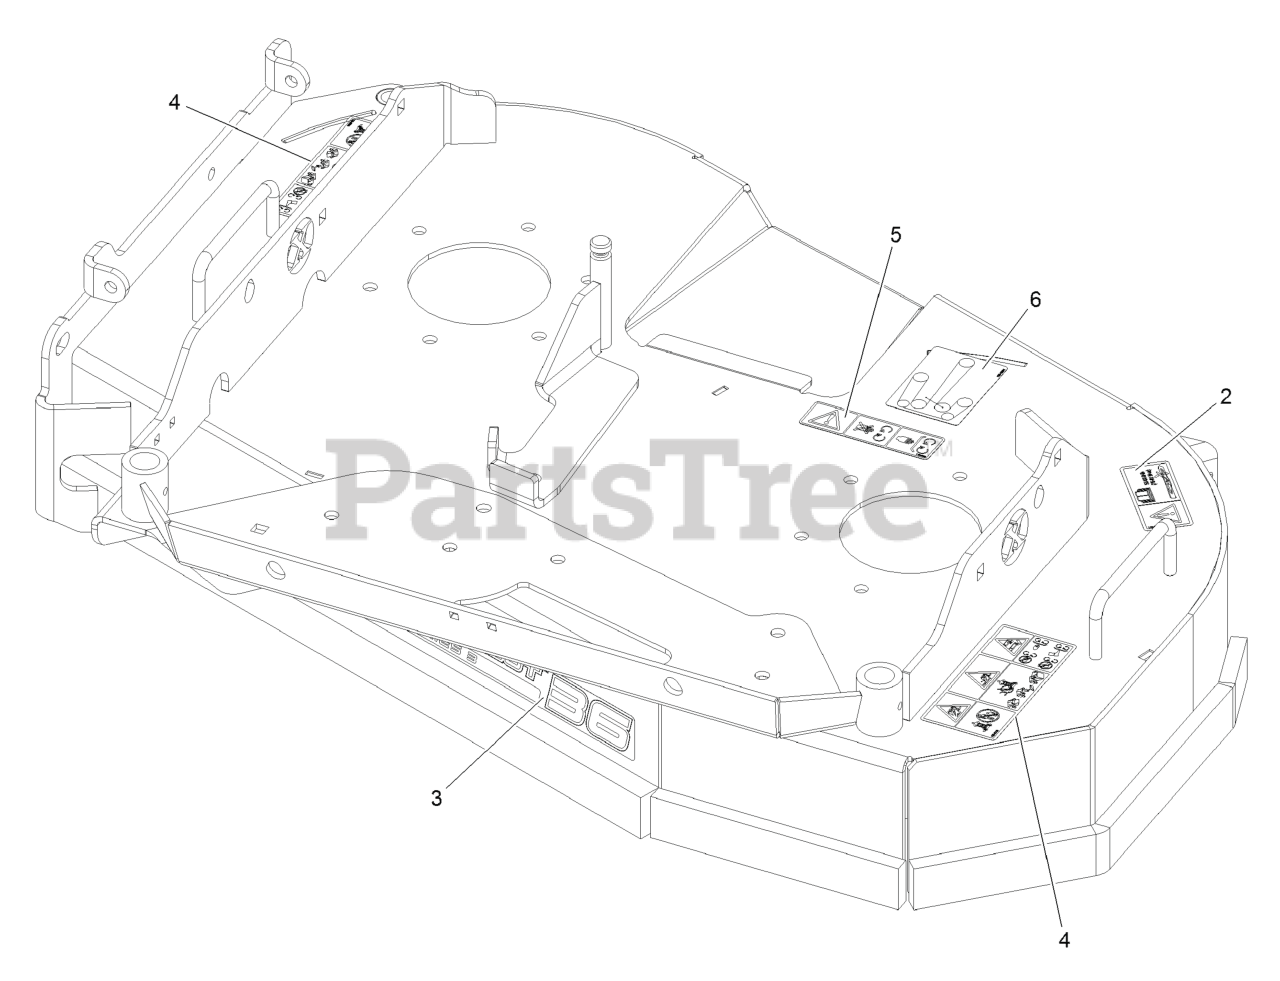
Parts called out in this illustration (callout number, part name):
2	DECAL-TORQUE, BOLT
3	DECAL-ULTRACUT 36 SERIES 3
4	DECAL-WARNING THROWN OBJ
5	DECAL-COVER, MISSING
6	DECAL-BELT ROUTING
